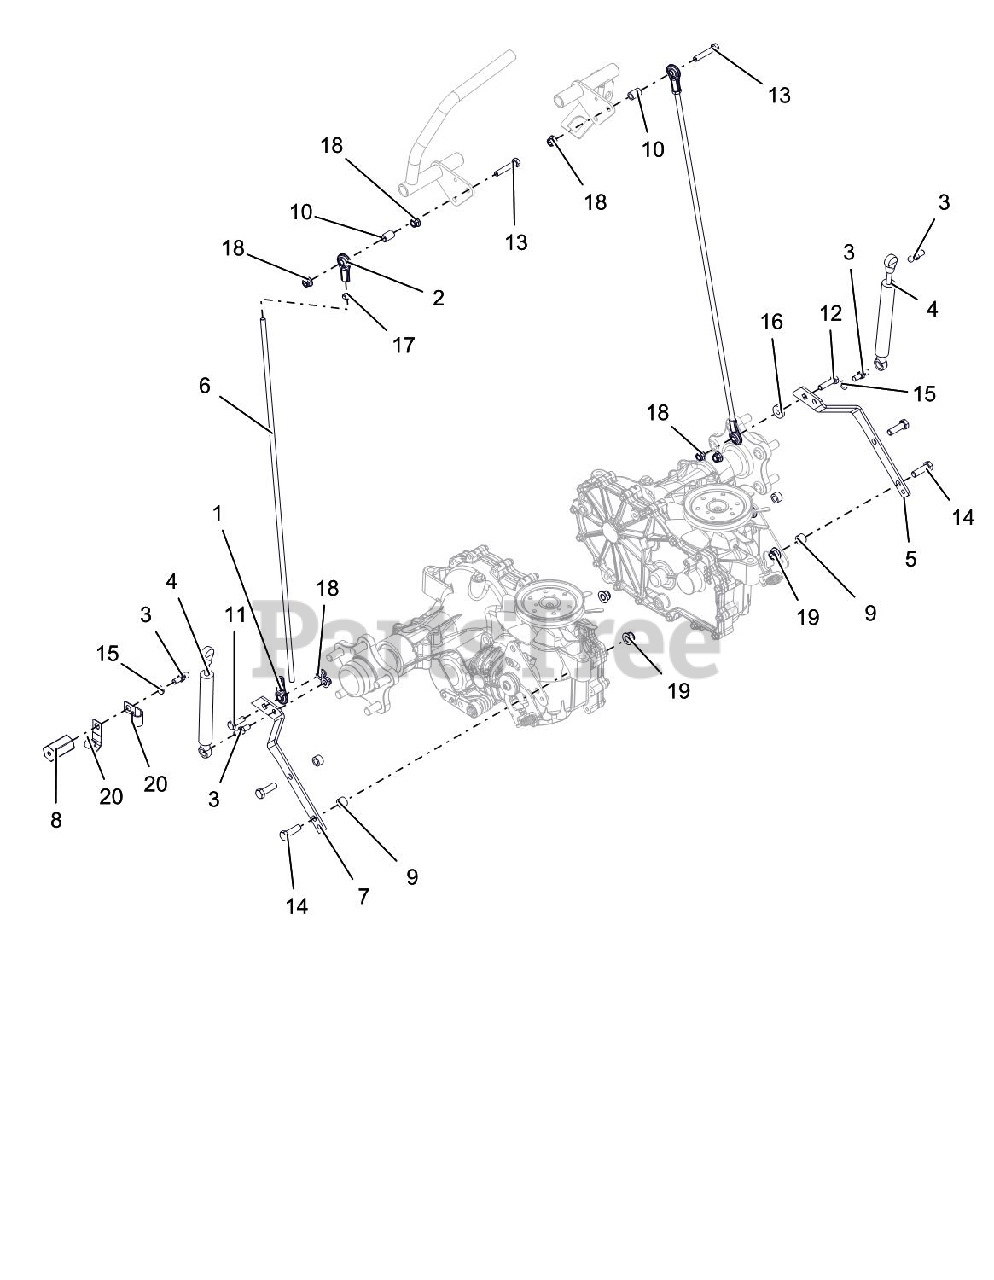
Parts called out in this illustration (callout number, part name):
1	ALIGNABALL, 5/16 RH THREAD
2	ALIGNABALL, 5/16 LH THREAD
3	STUD- BALL
4	DAMPER, CONTROL
5	BRKT, PROSTANCE CONTROL
6	ROD, STEERING
7	BRKT,PROSTANCE CONTROL-RH
8	MOUNT, DAMPER - PROSTANCE
9	BSHG-SLV .377X.624X.370
10	BSHG-SLV .328X.50X.75
11	@BLT-HEX .31-18X1.00 GR5 YWZC
12	@BLT-HEX .31-18X1.25 GR5 YWZC
13	@BLT-HEX .31-18X1.75 GR5 YWZC
14	@BLT-HEX .38-16X1.25 GR5 YWZC
15	@WSHR-LK .31X.078 REG YWZC
16	WSHR-FL-STL .328X.87X.179 YWZC
17	NUT-JAM LH .31-24 YWZC
18	@NUT-LK-NYL-FLG .31-18 YWZC
19	@NUT-LK-NYL-FLG .38-16 YWZC
